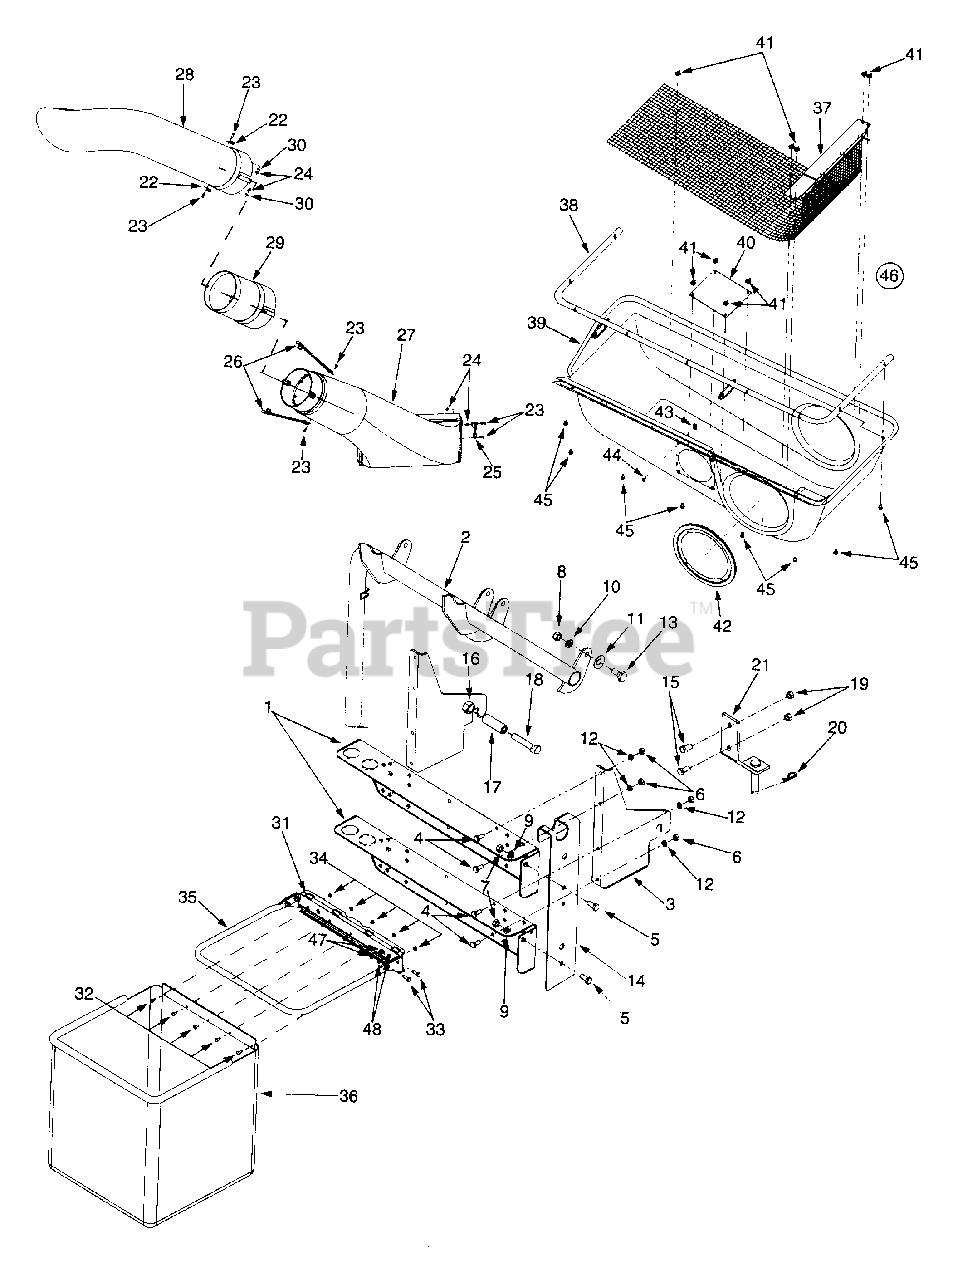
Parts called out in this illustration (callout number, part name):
5	Hex Bolt, 5/16-18 x .75"
6	Hex Nut, 1/4-20
7	Hex Nut, 5/16-18
8	Hex Nut, 3/8-16
9	Lock Washer, 5/16 I.D.
10	Lock Washer, 3/8 I.D.
11	Bell Washer, .51 I.D x 1.14 O.D. x .04
12	Lock Washer, 1/4 I.D.
13	Shoulder Screw, 3/8-16 x .5"
15	Flange Screw, 5/16-18 x 1"
16	Locknut, 1/2-13
17	Spacer
18	Cap Screw, 1/2-13 x 1.5"
19	Flange Nut, 5/16-18
20	Spring Cotter Pin
21	Hitch Bracket
22	Retainer Hook Bracket
23	Hex Bolt, 1/4-20 x .62"
24	Hex Lock Nut, 1/4 -20
25	Retainer Strap Assembly
26	Chute Strap
27	Discharge Chute
28	Grass Catcher Tube
29	Catcher Extension Tube
30	Spring Washer, .265 x .562 x .025
32	Truss Mach. Screw, #10-24 x .5"
33	Tap Screw, 1/4-28 x .875"
34	Hex Sems Nut, 10-24
36	Grass Bag
39	Grass Catcher Cover
40	Plastic Plate, 1/8 x 5.6" sq.
41	Zip Twist Fastener
42	Tube Seal
43	U-Type Speed Nut, #10-24
44	Truss B-Tap Screw, #10 x .5"
45	Hex Screw, 1/4-20 x .5"
46	Grass Catcher Cover Assembly
47	Hex Nut, 1/4-28
48	Lock Washer, 1/4" I.D.
